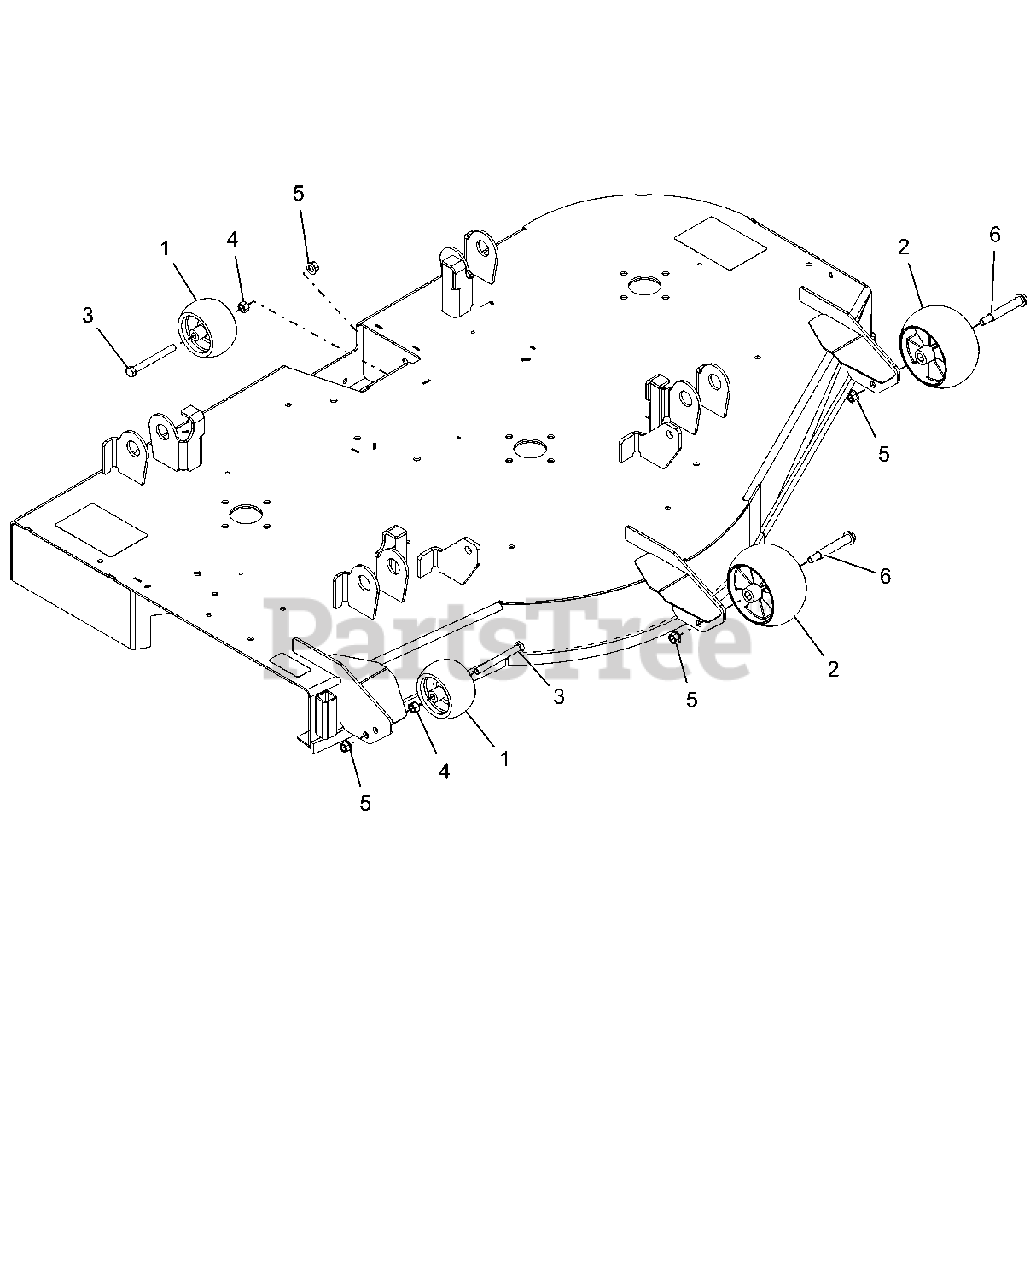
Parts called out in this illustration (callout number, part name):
2	ANTI-SCALP WHEEL - 5X OS
3	@BLT-HEX .38-16X3.50 GR5 YWZC
4	@NUT-HEX .38-16 YWZC
5	@NUT-LK-TOP-FLG .38-16 YWZC
6	BLT-SHLDR .38-16X2.50 HWH G5
